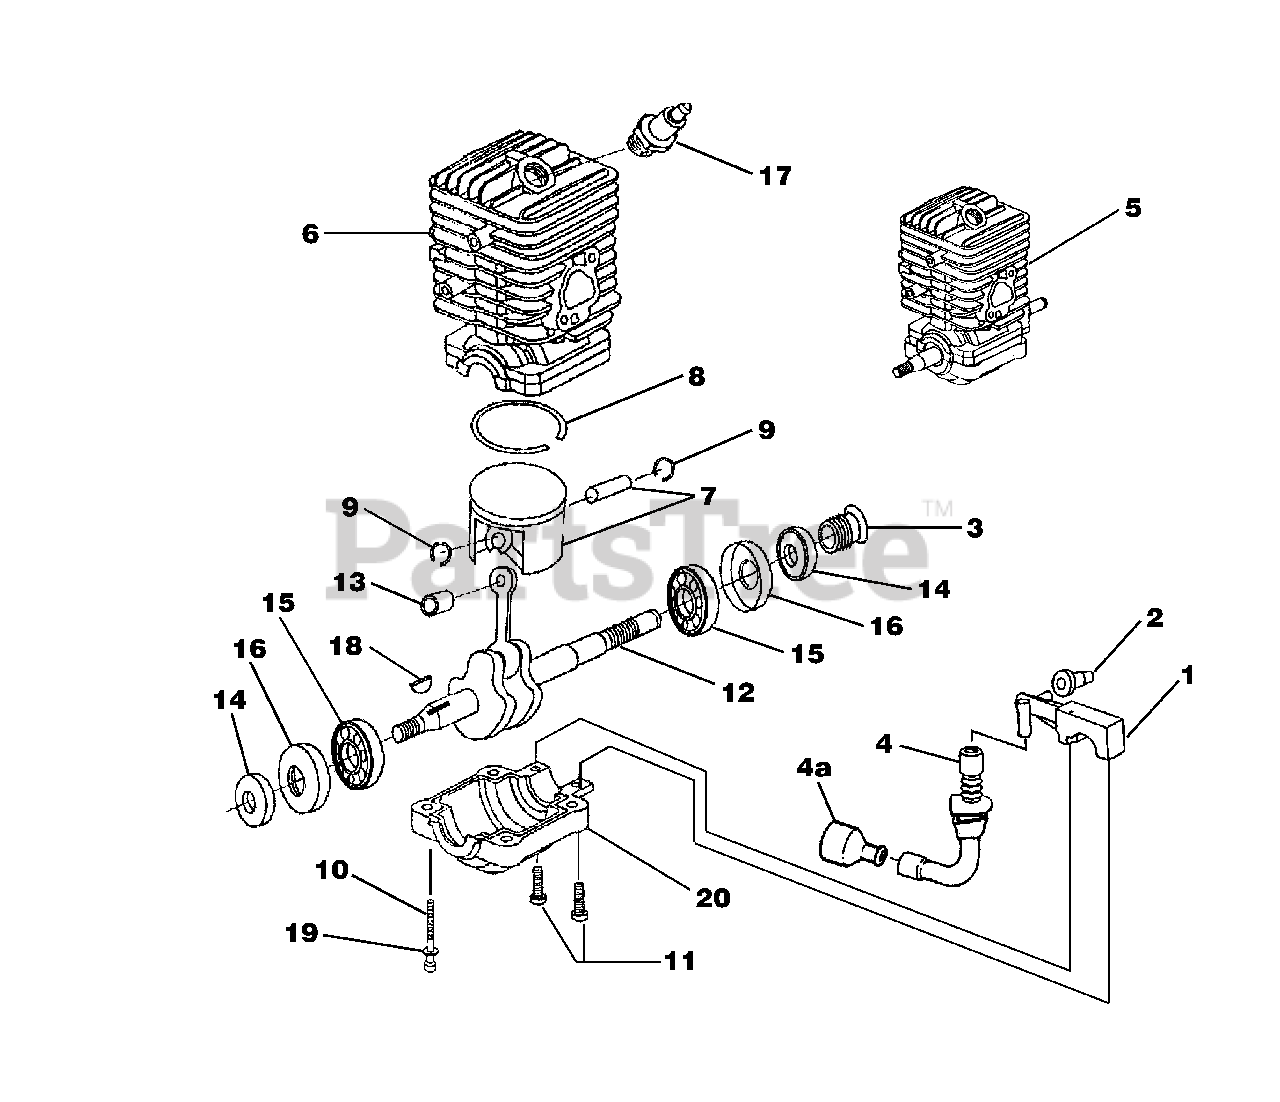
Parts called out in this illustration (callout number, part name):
1	Oil Pump Kit
2	Grommet, Oil Outlet
3	Left Hand Worm
4	Tube, Oil Intake
4A	Oil Filter
5	Short Block, Complete (33cc)
6	Cylinder Kit (33cc)
7	Piston & Pin (33cc)
7	Piston & Pin (38cc)
8	Piston Ring
9	Ring, Retaining
10	Screw, Cap-Socket Hd. (10-24 x 2")
11	Screw, Pan Hd., Plastite (8-16 x 5/8")
12	Crankshaft & Rod Assembly
13	Bearing, Needle
14	Shaft Seal
15	Bearing & Rubber Case
16	Rubber Case
17	Spark Plug
18	Woodruff Key
19	Washer
20	Lower Crankcase
